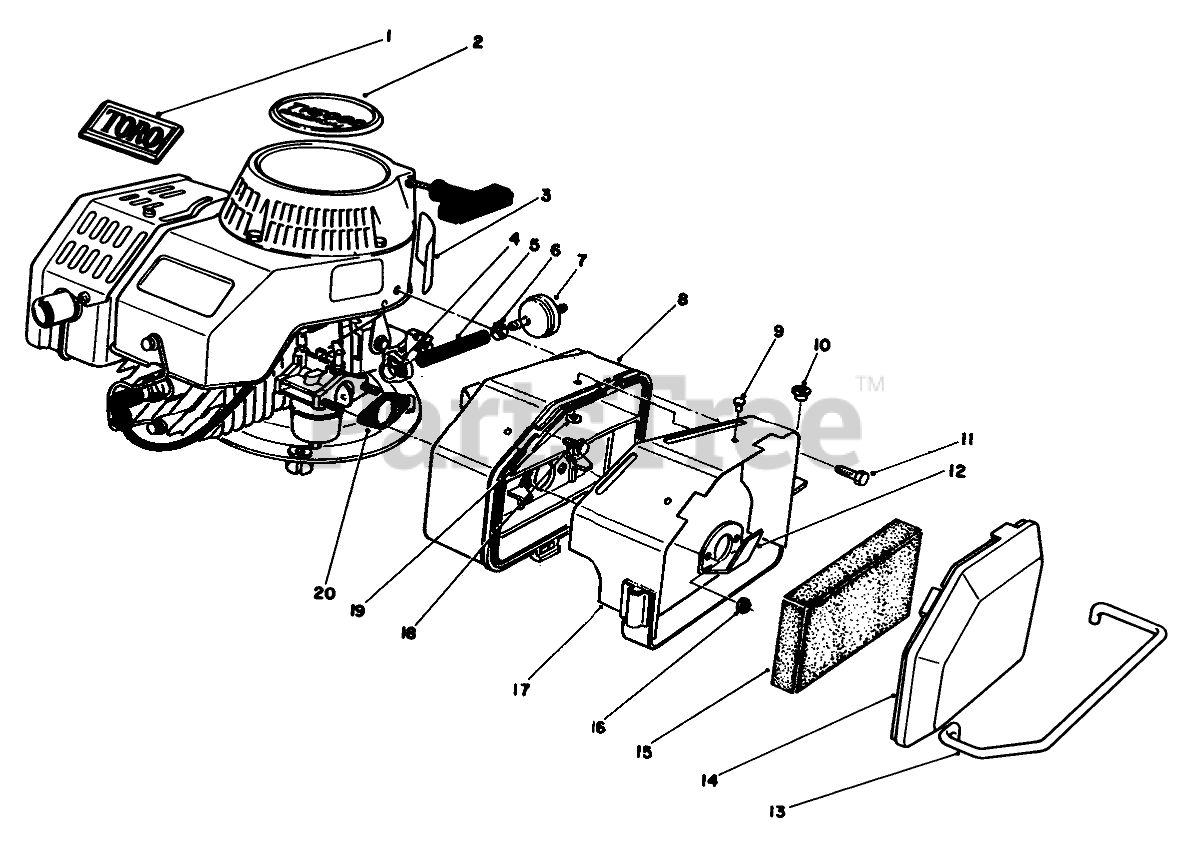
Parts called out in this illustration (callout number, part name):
1	Plate-Logo
2	Plate-Engine Logo
3	FUEL MIX DECAL
4	FUEL LINE CLAMP
5	LINE-GAS
6	FUEL HOSE CLAMP
7	Nut
8	Air Cleaner Assembly (Incl. Ref. #9, 17 & 19)
9	NUT-HEX
10	5/16 ID BSHG
11	SCREW-HHF
12	SPIT BACK DEFLECTOR
13	AIR CLEANER GUARD
14	AIR CLEANER COVER
15	FILTER
16	NUT-LOCK
17	AIR CLEANER COVER WA
18	HEX FL HD M.6X1.0X25MM
19	WASHER-FLAT
20	GASKET-AIR CLEANER
